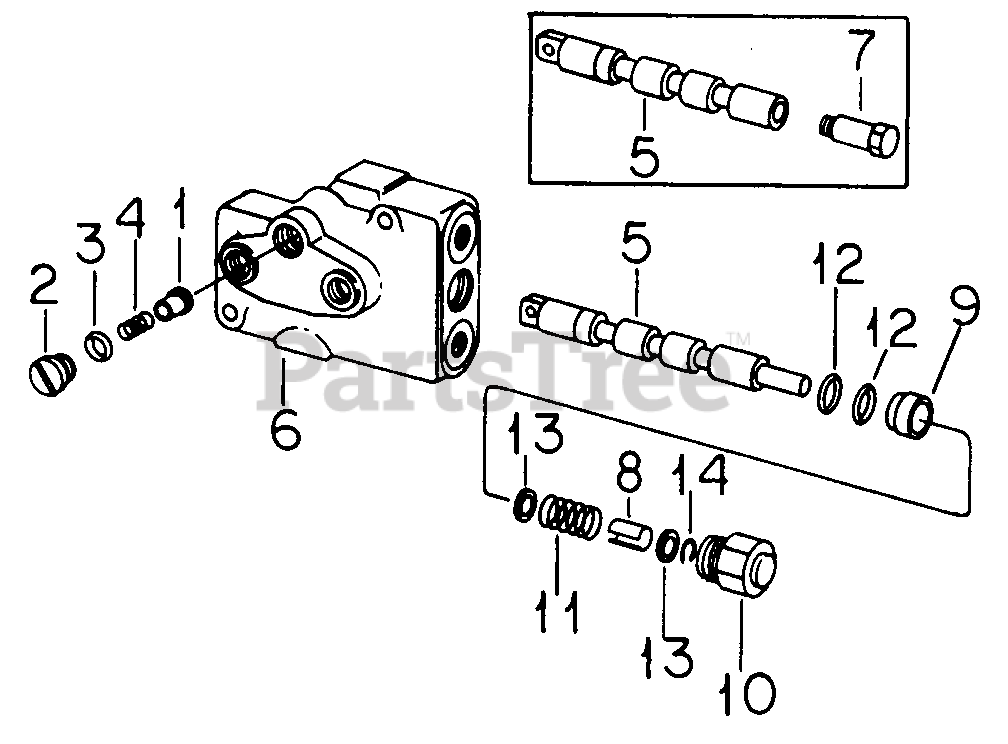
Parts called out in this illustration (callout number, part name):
1	Plunger, Lift Check
2	Plug, Lift Check
3	O-Ring, 3/8 X 9/16 X 3/32
4	Spring, Lift Check
5	Spool - Not Serviced Separately
6	Body - Not Serviced Separately
7	Not used in this application
8	Spacer, Spool
11	Spring, Spool Center
12	O-Ring, 1/2 X 11/16 X 3/32
13	Washer, .020
14	Ring, Retainer
